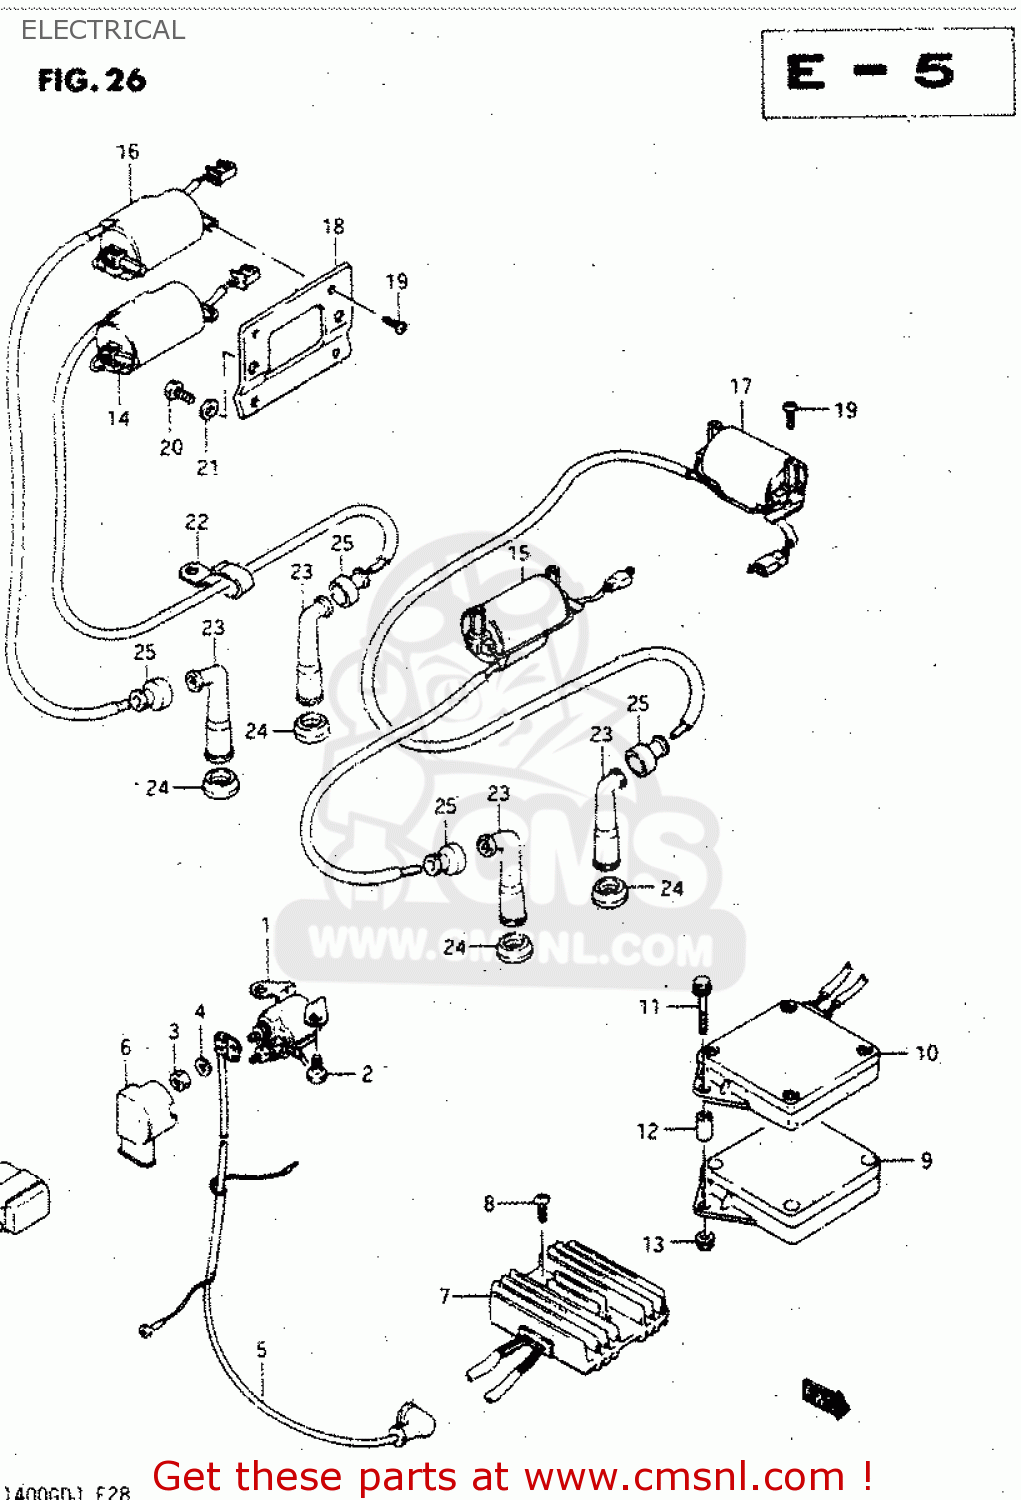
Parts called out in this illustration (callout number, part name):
1	RELAY ASSEMBLY,STARTING MOTOR
2	BOLT
3	NUT
4	LOCK WASHER
5	WIRE,STARTER MOTOR LEAD
6	CAP,STARTER RELAY TERMINAL
7	RECTIFIER ASSY
8	SCREW
9	IGNITER UNIT
10	IGNITER UNIT
11	BOLT
12	SPACER (6.4X9X21.5)
13	NUT
14	COIL ASSEMBLY,IGNITION
15	COIL ASSEMBLY,IGNITION NO
16	COIL, IGNITION NO.3
17	COIL ASSEMBLY,IGNITION
18	BRACKET,IGNITION COIL
19	SCREW 5X12
20	BOLT 8X12
21	WASHER 8MM
22	CLAMP
23	CAP ASSY,SPARK PLUG
24	SEAL,SPARK PLUG
25	SEAL,SPARK PLU
26	RELAY ASSY,FUEL CUT
